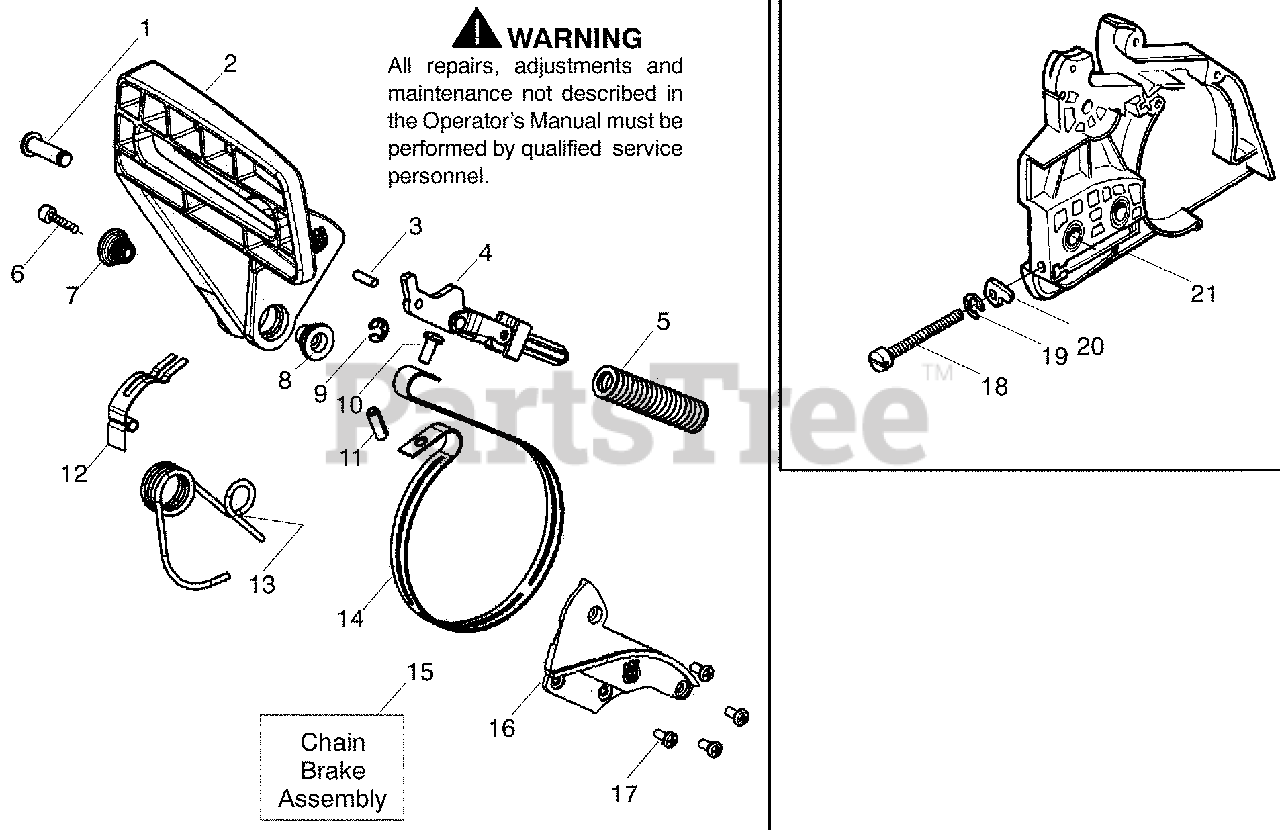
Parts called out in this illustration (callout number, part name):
1	Pin--Pivot
2	Kit-- Lever & Link Assy.
4	Assy--Front Link
5	Spring--Chain Brake
7	Journal--Right
8	Journal--Left
10	Screw
11	Pin--Spring
12	Spring--Position
13	Spring--Handguard
14	Band--Brake
15	Assy--Chain Brake
16	Cover--Chain Brake Spring
17	Screw
18	Screw--Bar Adjusting
20	Pin--Bar Adjusting
21	Cover--Clutch
